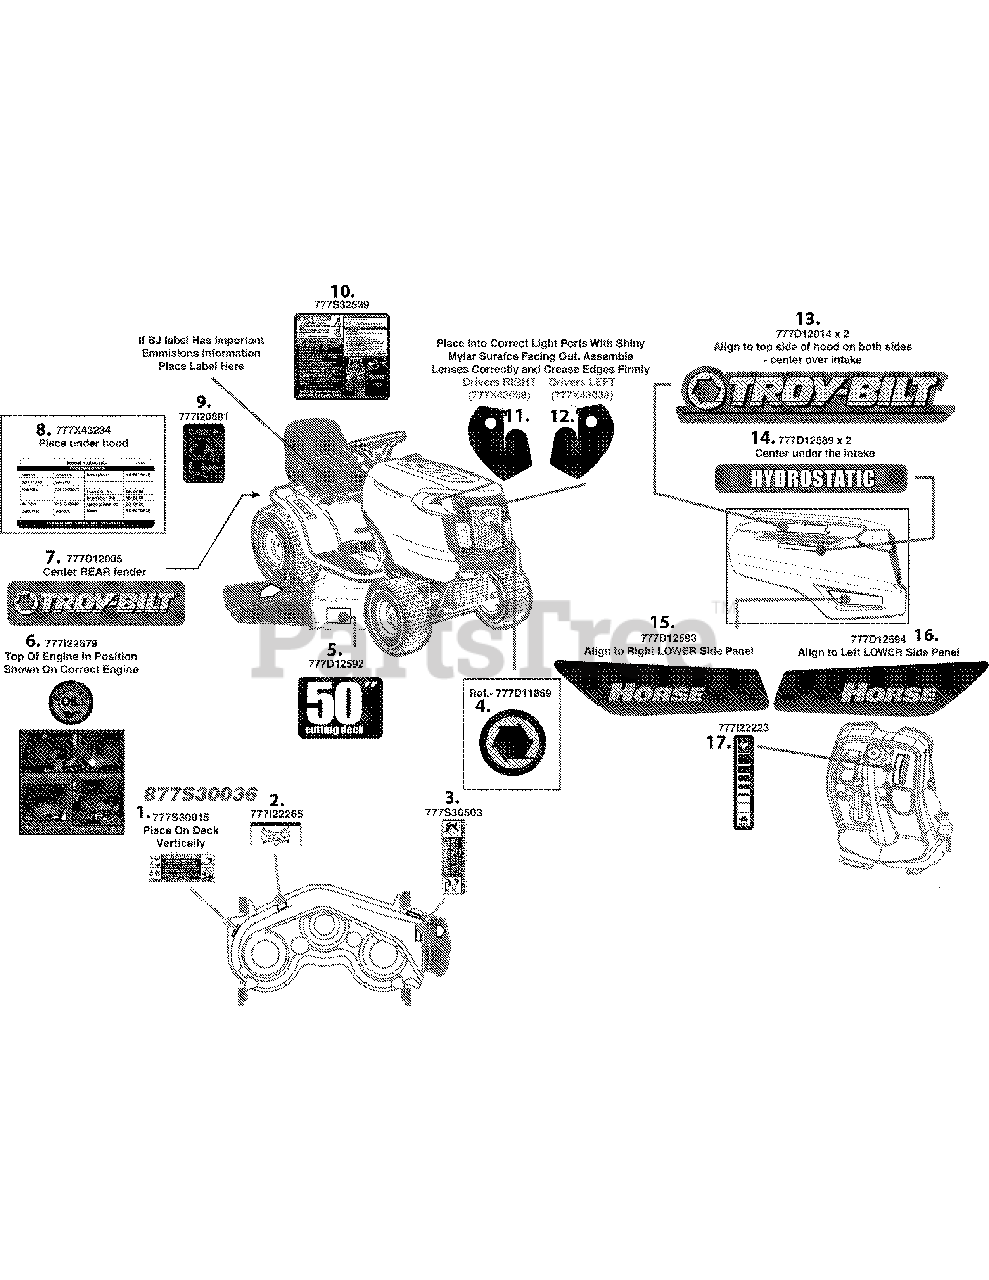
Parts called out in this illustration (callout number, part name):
1	LABEL:RIDER DNGR.STRAIGT
2	LABEL-BELT ROUTE
3	LABEL-DANGER CHUTE
4	LABEL-EMBOSSED TROYBILT
5	LABEL:RIDER/DK:TBILT:50
6	LABEL-CHECK ENG OIL
7	LABEL-RIDER REAR FENDER TROY
8	LABEL:RIDER:PARTSLIST:13AP61KP
9	LABEL-HITCHPLATE
10	LABEL:RIDER:SAFETY HYDRO
11	LABEL-RIDER K STYLE RH
12	LABEL-RIDER K STYLE LH
13	LABEL-RIDER HOOD K STYLE TROY
14	LABEL:RIDER:KSTYHOOD:HYDRO
15	LABEL:RIDER:RTLOWHDSD
16	LABEL:RIDER:LFTLOWHDSD
17	LABEL-DASH RH
